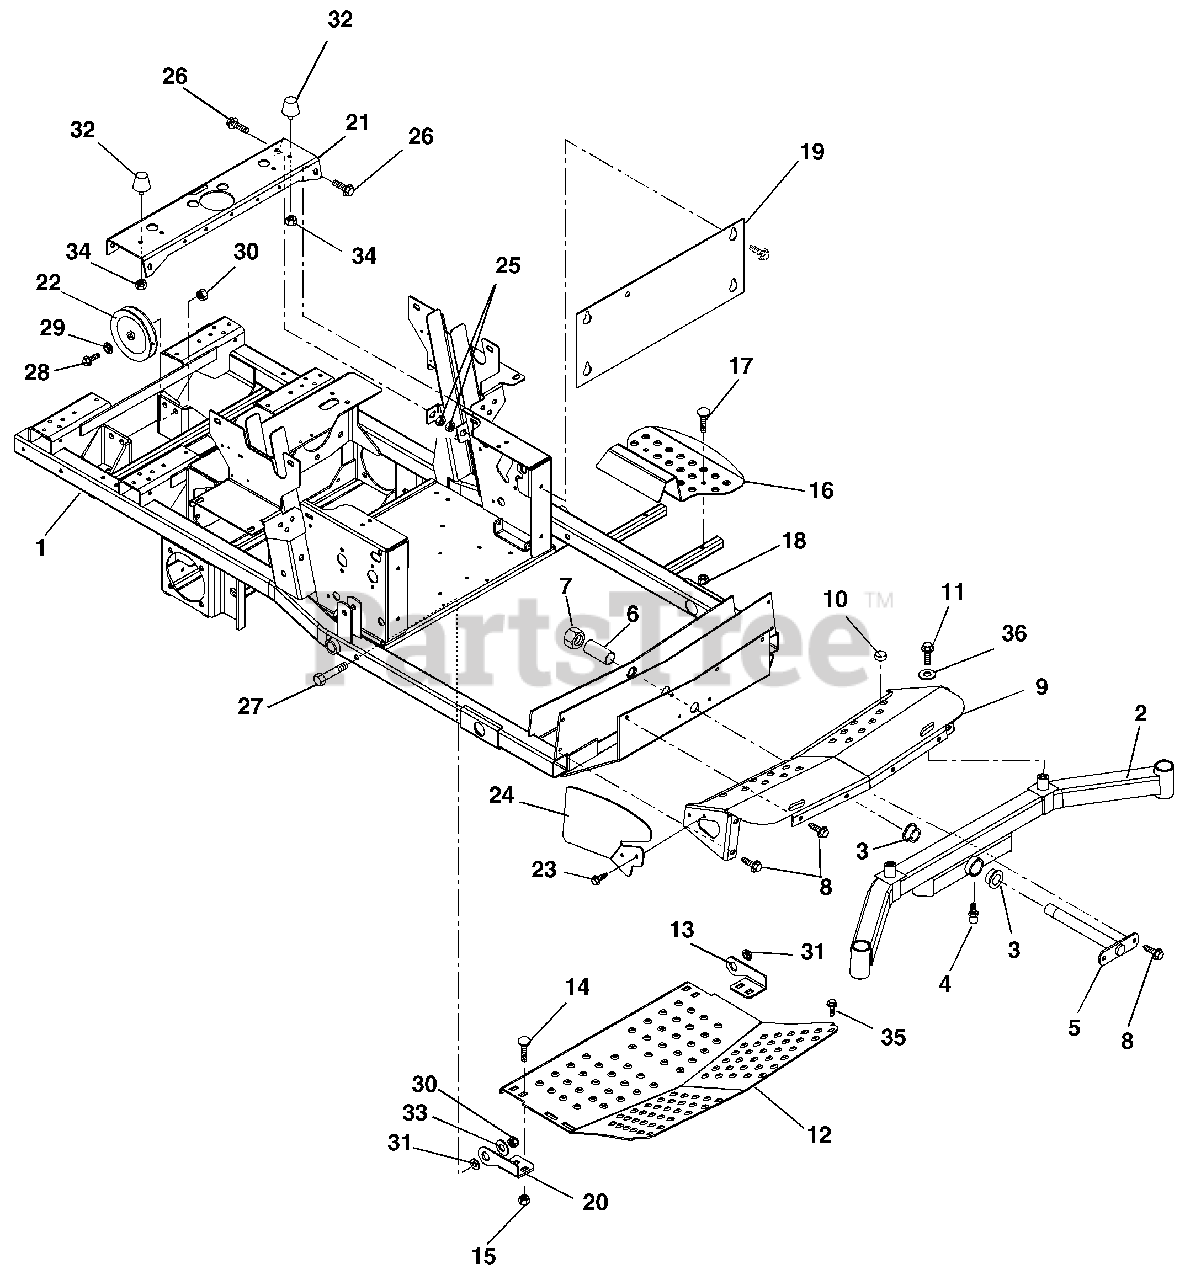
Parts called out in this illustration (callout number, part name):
1	Weldment, Frame
2	Weldment, Front Axle
3	Bushing, Flange 1.020 x 1.385 x .75 x 1.75
4	Fitting, Lube .25-28 x .256
5	Pin, Axle
7	Nut, Locking Nylon 1.0-14
8	Screw, Tapping .38-16 x .75
9	Weldment, Axle Cover
10	Button, Bumper
11	Bolt, Hex .50-20 x 1.00 Grade 5
12	Panel, Inspection
13	Hinge, Footboard Left Hand
14	Bolt, Round Head Square Neck .38-16 x 1.00 Grade 5
15	Nut, Locking Top Flange .38-16
16	Step, Ingress
17	Bolt, Round Head Square Neck .31-18 x 1.75 Grade 5
18	Nut, Locking Top Flange .31-18
19	Plate, Kick
20	Hinge, Footboard Right Hand
21	Channel, Cross
22	Pulley, Idler
23	Screw, Tapping .25-20 x .50 Hex Washer Head
24	Guard, Foot
25	Nut, Retainer .375-16 x .37
26	Bolt, Serrated Flange Washer Head .38-16 x 1.00
27	Bolt, Hex .50-13 x 3.25 Grade 5
28	Bolt, Hex .50-13 x 2.25 Grade 5
29	Washer, Flat Steel .505 x .88 x .072
30	Nut, Locking Top Flange .50-13
31	Bushing, Flange .515 x .75 x .275 x 1.12
33	Washer, Flat Steel .563 x 1.38 x .109
34	Nut, Locking Flange .312-24
35	Screw, Tapping Hex Washer Head .38-16 x 1.00 (318, 319)
36	Washer, Flat Steel .518 x 2.00 x .105
